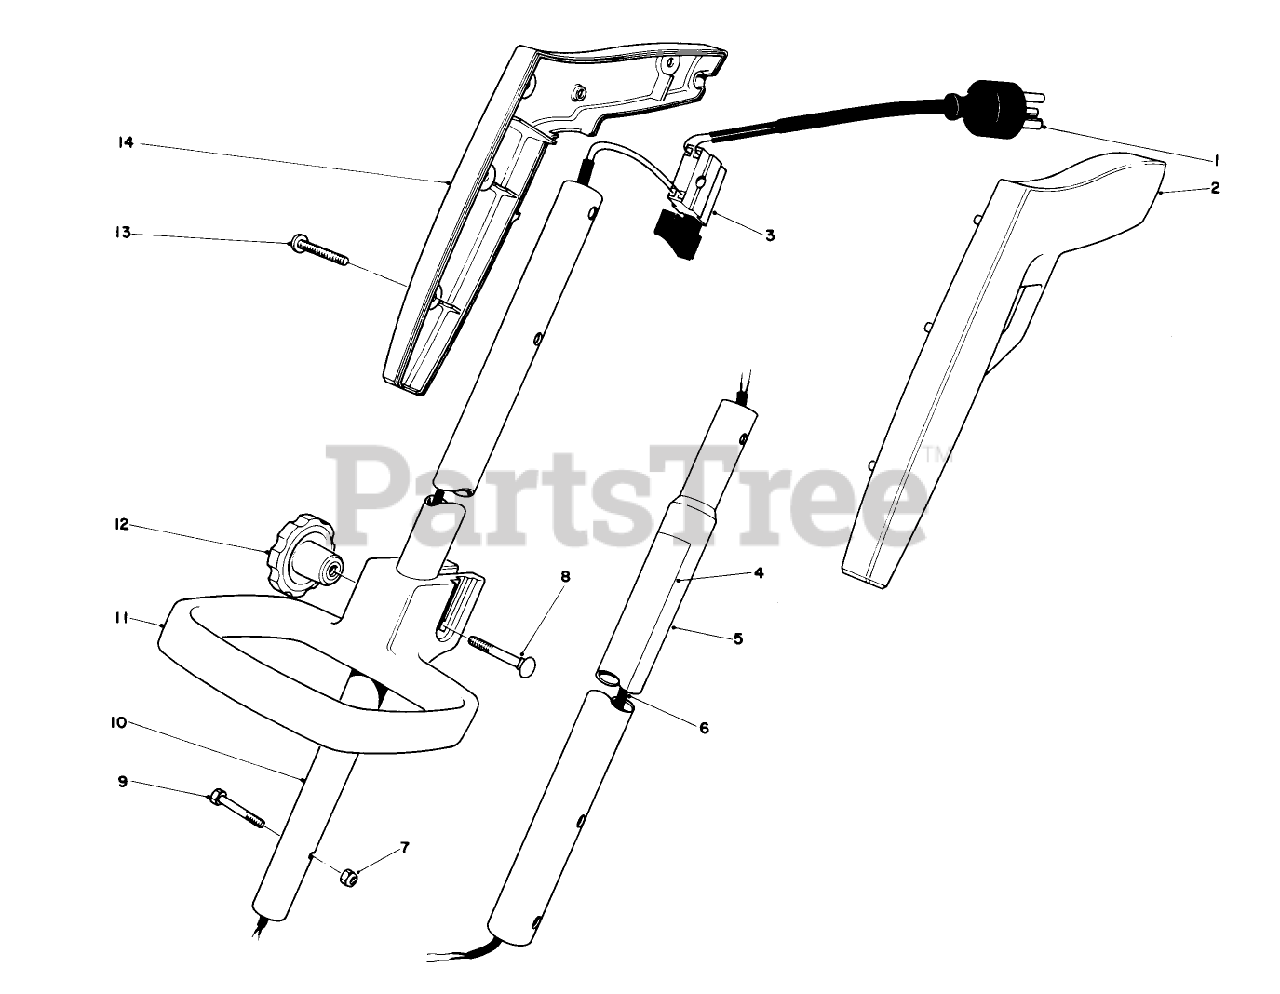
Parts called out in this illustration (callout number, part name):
1	Wiring Harness-Upper
2	Grip L.H.
3	SWITCH SINGLE SPEED
4	Caution Decal
5	Tube-Lower
6	Wiring Harness
7	NUT-LOCK, NI
8	BOLT-CARR
9	HEX HD MACHINE SCREW
10	Tube-Upper
11	ADJUSTABLE HANDLE
14	R.H. GRIP
